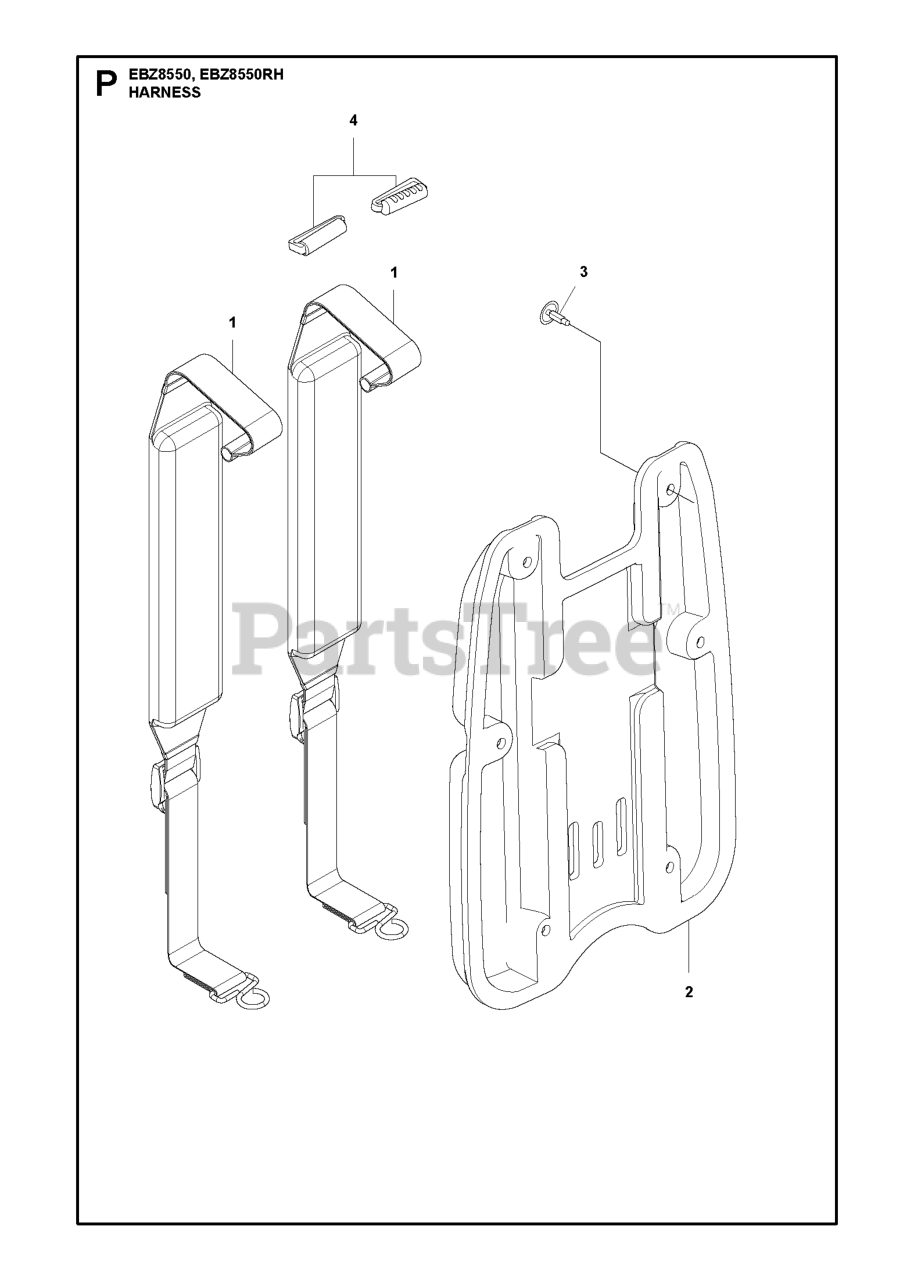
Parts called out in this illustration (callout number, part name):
1	BAND ASSY (RPLS 848L583611)
3	CLIP
4	CLIP
